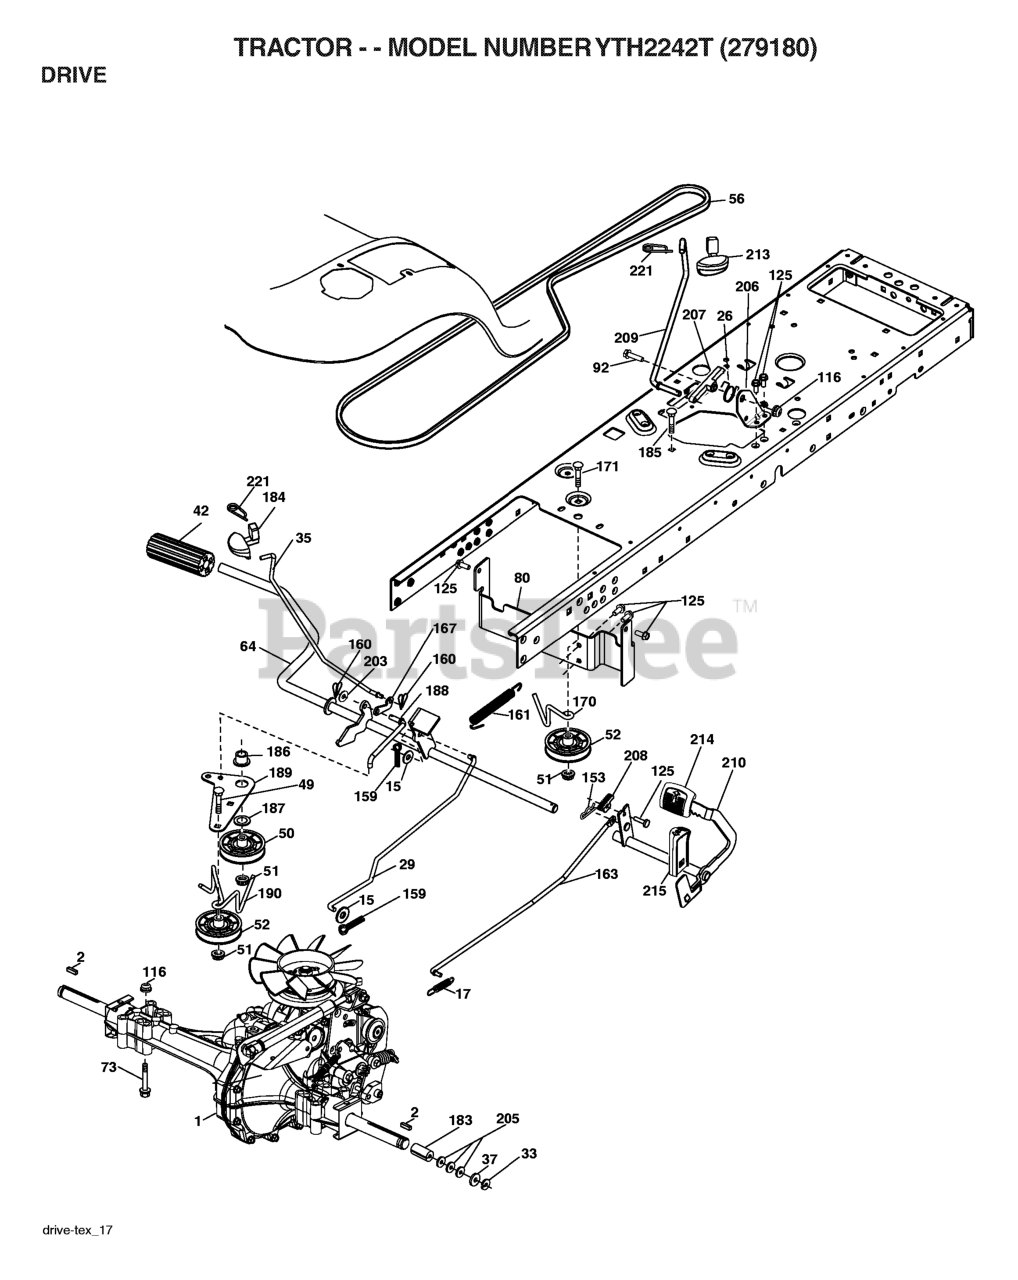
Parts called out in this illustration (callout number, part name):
2	SQUARE KEY
15	WASHER
17	SPRING.BRAKE.HG3000/3500
29	ROD.BRAKE.HG-0510
35	ROD.BRAKE.PARKING.GT.H
42	PEDAL COVER T
50	IDLER.FLAT.910.OFFSET
51	NUT LOCK FLG 3/8-16 UNC
52	IDLER.V-GROOVE.910.OFFSET
61	PULLEY TRANS
64	SHAFT.ASM.PEDAL.BRK.CNTR
73	BOLT HEX 5/16-18 GR 5
80	BRKT.STRP.TRQ.LT.HYD.C
92	BOLT
116	NUT LOCK HEX FLANGE 5/16-18
125	SCREW
153	RETAINER M
159	COTTER PIN
160	RETAINER CLIP
161	SPRING.RETURN.CLUTCH.2006
163	ROD.PEDAL.CONTROL.0510
166	NUT.PUSH.625.2006
167	LATCH.BRAKE.SPRING
170	KEEPER.V-IDLER.CENTER.
183	SPACER AXLE
184	HANDLE.PARKG.BRK.HUSQ X667
186	SPACER.RETAINER
187	WASHER 12/32X2X10GA
188	RP.LINK.CLUTCH.GROUND.DRIVE
189	BELLCRANK.GROUND.DRIVE.TEX.
190	KEEPER.BELLCRANK.DRIVE
196	SCREW 3/8-16X1
197	LINK.CLUTCH.ANIT-ROTAT
198	SCREW.7/16-14X7/8.FLAN
203	WASHER
206	BRKT.MOUNT.LATCH.CRUIS
207	LATCH.CONTROL.CRUISE
208	GEAR.SECTOR.CONTROL.CR
209	ROD.CONTROL.CRUISE.GT.
210	ROCKER.ASM.PEDAL.CONTR
211	BEARING.NYLON
213	KNOB.CONTROL.CRUSIE.HU
214	PEDAL.FORWARD.TEX.GT.4
215	PEDAL.REVERSE.TEX.GT.4
220	REFLECTOR.RH.TEX GT
221	RETAINER.SPRING.CLIP.H
222	WASHER
